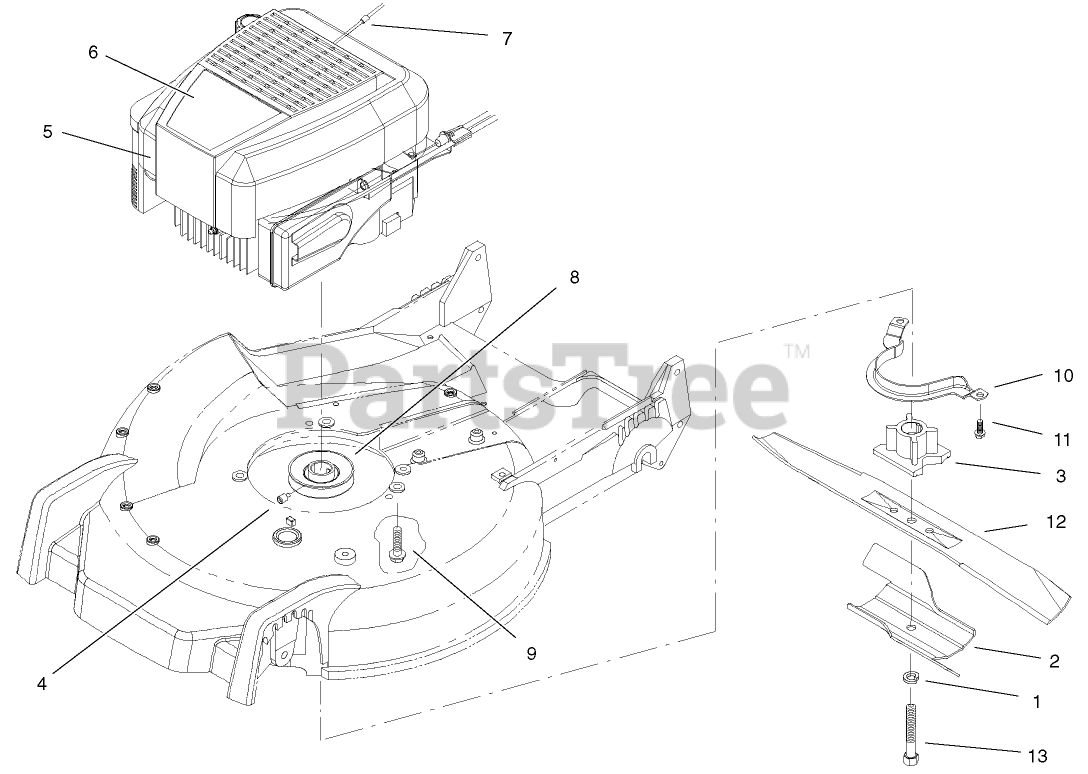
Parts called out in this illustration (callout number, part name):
1	WASHER-LOCK
2	ACCELERATOR-BLADE
3	RETAINER-BLADE
7	STOP-ROPE
8	PULLEY
9	SCREW-HWH
10	BRACKET-GUIDE, BELT
11	SCREW-HWHTF
